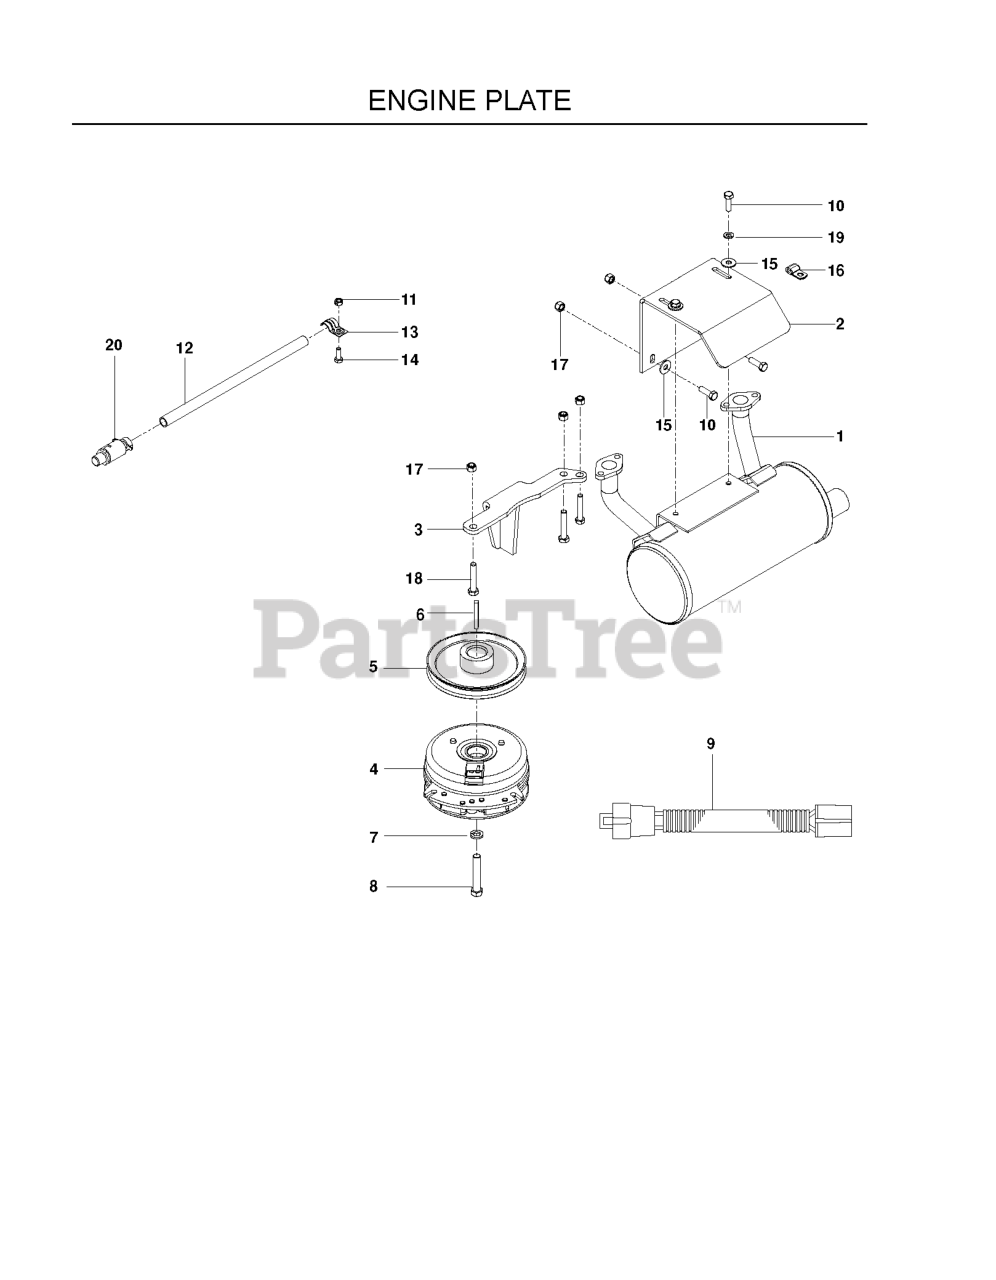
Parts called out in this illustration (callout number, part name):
1	MUFFLER KOHLER GEN II
2	MUFFLER BRACKET BLACK
3	WLDT, CLUTCH TIE DOWN BLK
4	ELECTRIC CLUTCH W/CABLE
6	KEY 1/4" SQ X 1 7/8"
7	WASHER 7/16 LOCK
8	BOLT 7/16F X 2 1/2
9	KOH PIGTAIL
10	HCS 5/16C X 1
11	NUT 1/4C CENTER LOCK
12	OIL DRAIN HOSE
14	HCS 1/4C X 3/4 HCS
15	WASHER 5/16 FLAT
16	DOUBLE TUBE CLAMP
17	NUT 5/16 NYLOC
18	HCS 5/16C X 1 3/4
19	WASHER.LOCK.HVY.HLCL.SPR.5/16
20	OIL DRAIN FITTING
